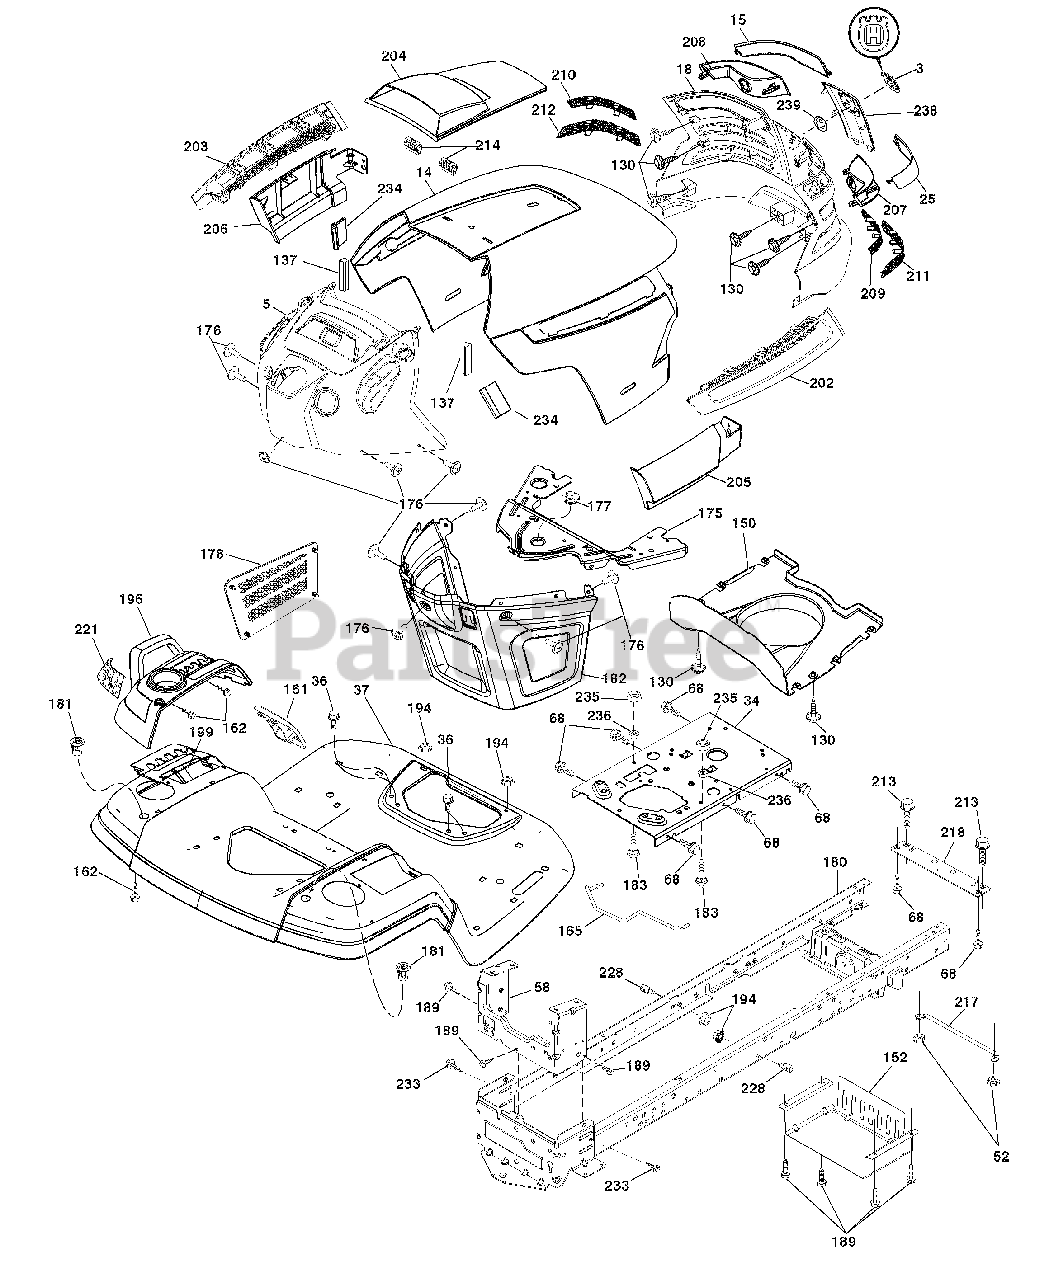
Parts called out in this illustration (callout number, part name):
3	Logo
14	Hood
18	Grille/Lens Asm.
34	Plate Engine
36	Screw 5/16-18 x 3/4
37	Fender
52	Nut Lock 5/16-18
58	Drawbar Upper
68	Screw Thdrol. 5/16-18 x 1/2
130	Screw #10 x 0.750
137	Bumper Dash
152	Shield Browning
161	Console Fuel Window
162	Screw
165	Support Tank Rear
175	Crossmember
176	Screw 10-24 x 5/8
177	Bushing Steering
178	Cargo Net Asm.
181	Bushing Mtg. Fender Crgo
182	Dash Lower
183	Bolt Fin. Hex 5/16-18 unc x 1-1/4
189	Screw 5/16-18 x 3/4
194	Nut Lock Hex Flange 5/16-18
196	Console Asm. Deck Lift
199	Plate Deck Lift
202	Vent Side Hood RH
203	Vent Side Hood LH
204	Vent Top Hood
205	Skirt Hood Side RH
206	Skirt Hood Side LH
209	Insert Hex Top RH
210	Insert Hex Top LH
211	Insert Hex Bottom RH
212	Insert Hex Bottom LH
213	Bolt 5/16-18 x 3/4
214	Clip Retainer
218	X-Piece Hood Stop
221	Reflector LH
228	Stud Fastner
233	Bolt Shoulder
234	Bumper Hood
235	Spacer Fender
236	Nut Lock 5/16-18 unc
